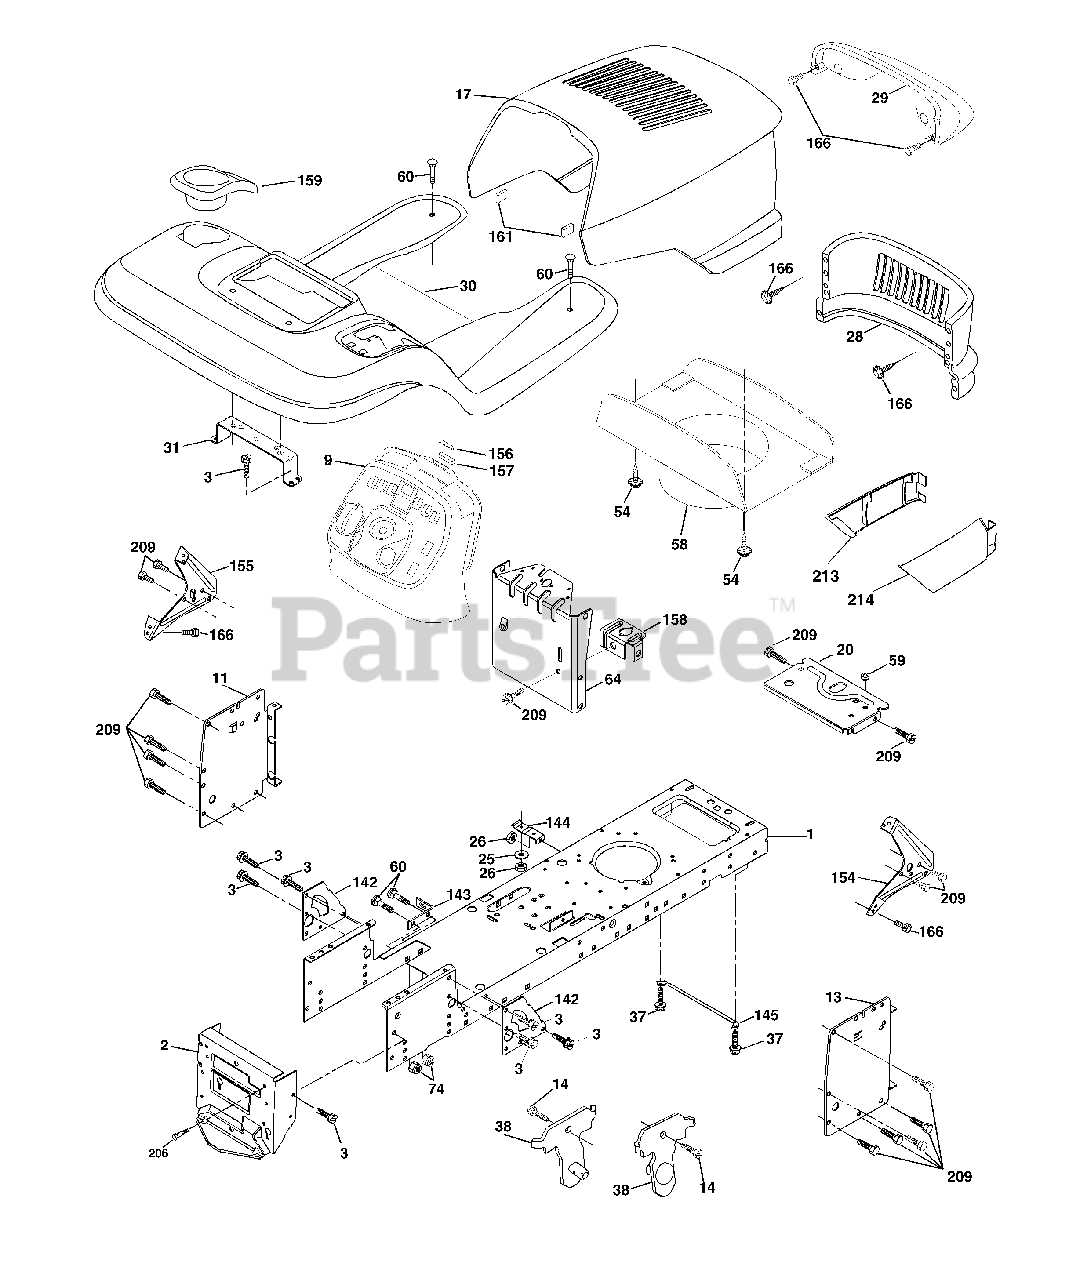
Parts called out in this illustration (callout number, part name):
1	Chassis
2	Drawbar
3	Screw 3/8-16x3/4
9	Dash
11	Panel Dash Lh
13	Panel Dash Rh
14	Screw Thdrol 3/8-16 x 1/2
17	Hood
20	Plate Battery
25	Washer 13/32 X 13/16 X 12 Ga
26	Nut Lock Hex W/Ins 3/8-16 Unc
28	Grille
29	Lens
31	Bracket Fender
37	Screw Thdrol 6/16-18 x 1/2 TYT
38	Bracket, Asm. Pivot Mower Rear
54	Screw Hex Wshd 8-18 x 7/8
58	Duct Hood
59	Bushing Snap
60	Bolt Rd Hd Sqnk 3/8-16 Unc x 3/4
64	Dash Lower
74	Nut Crownlock 3/8-16 Unc
142	Plate Reinforcement STLT
143	Bracket Swaybar Chassis
144	Bracket Footrest
145	Rod Pivot Chassis/Hood
154	Bracket Dash Rh
155	Bracket Dash Lh
156	Striker Plate
157	Magnet Stealth
158	Bracket Parking Brake
159	Cupholder
161	Extrusion Bumper
166	Screw Hw Hd Hi-Lo #13-16 x 3/4
206	Bolt Shoulder 5/16-18
209	Screw Hexwsh Thdrol 3/8-16 x 3/4
213	Skirt Grille Lh
214	Skirt Grille Rh
